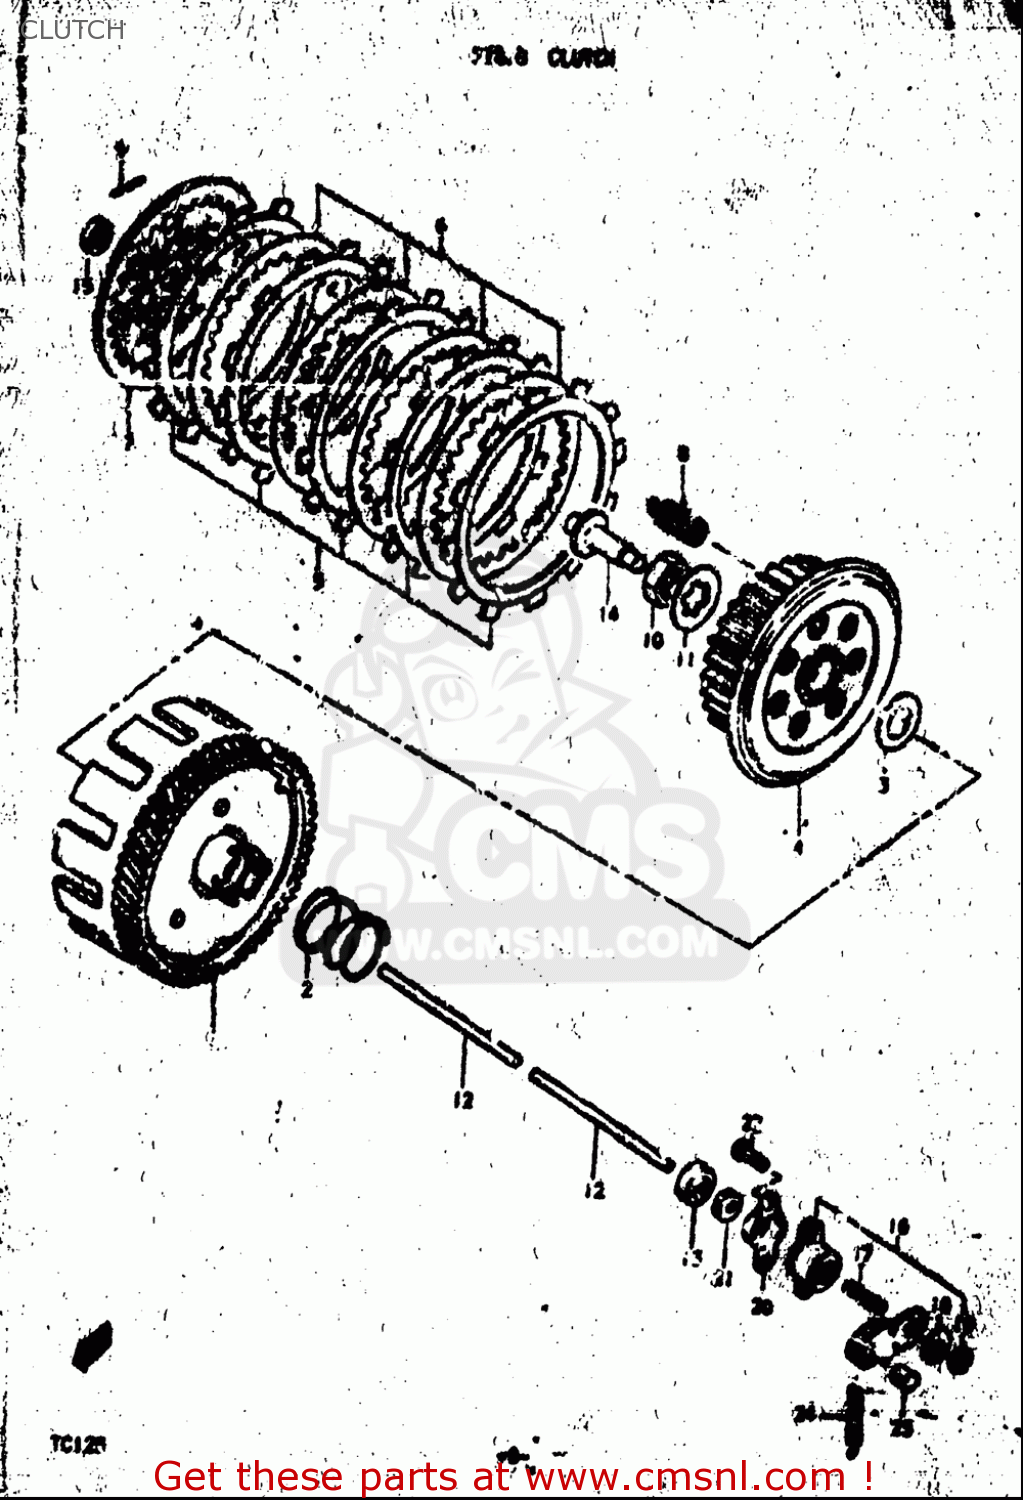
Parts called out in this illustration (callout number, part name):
2	SPRING
3	WASHER
4	HUB,CLUTCH SLEEVE
5	PLATE,CLUTCH DRIVE(T:3.0) (NAS)
6	PLATE,CLUTCH DRIVEN (NAS)
7	PLATE,CLUTCH PRESSURE
8	SPRING
9	PIN(2.5X19.8)
10	NUT
11	WASHER,LOCK
12	ROD,CLUTCH PUSH,L
13	SEAL,OIL(6X19X7)
14	ROD,CLUTCH RELEASE
15	SEAL,OIL (10X17X5)
16	SCREW ASSY,CLUTCH RELEASE
18	WASHER(6.5X16X1.2)
19	NUT
20	COVER,CLUTCH RELEASE SCREW
21	SEAL,DUST(5.3X13X5)
22	SCREW
23	PIECE,RELEASE ARM END
24	SPRING
